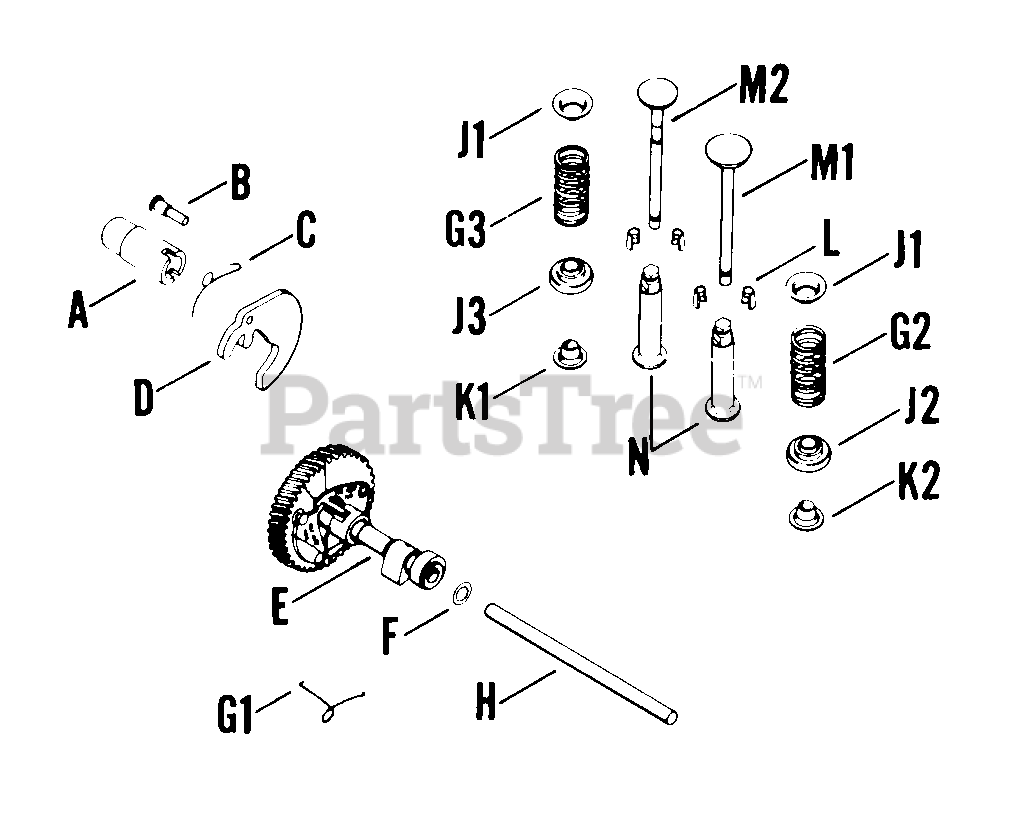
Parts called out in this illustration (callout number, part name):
C	SPRING - DISCONTINUED
E	CAMSHAFT - USE 47 010 06
F	SPACER (.005")
F	SPACER (.010")
G1	SPRING, ACTUATING-DISCONTINUED
G2	SPRING, EXHAUST VALVE-(#DSC)
G3	SPRING, EXHAUST VALVE-(#DSC)
H	PIN - USE 235193
J1	RETAINER, SPRING
K1	RETAINER, VALVE SPRING
K2	RETAINER, VALVE SPRING
L	KIT, RETAINER
M1	VALVE, INTAKE - DISCONTINUED
